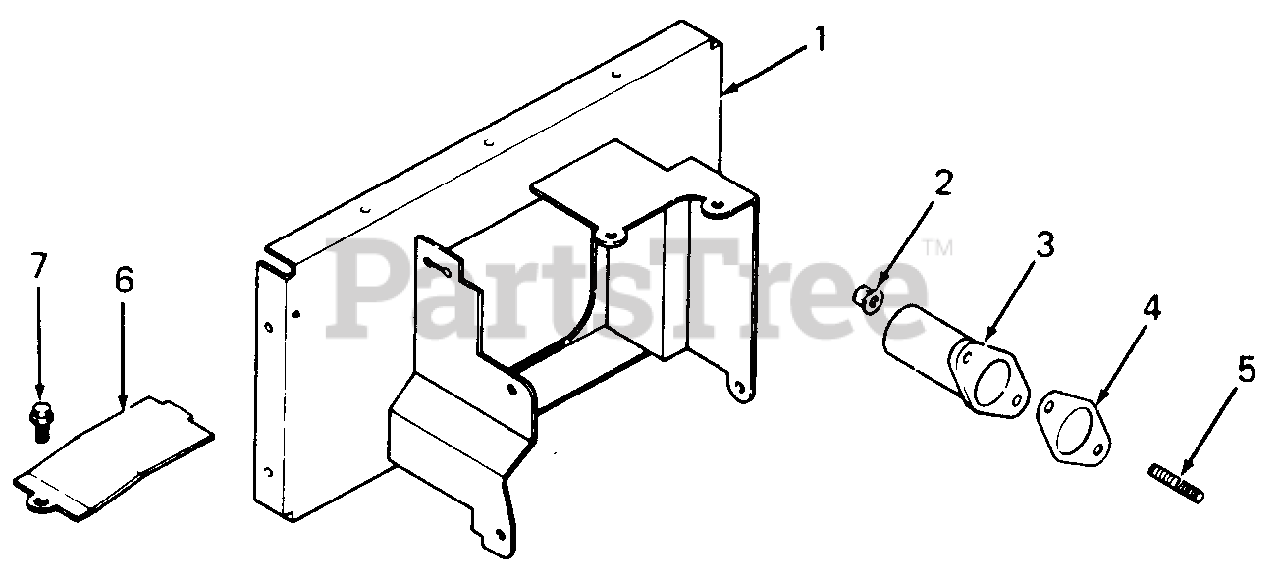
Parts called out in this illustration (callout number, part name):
1	Baffle, Ducted Air
2	Nut
3	Manifold, Exhaust
4	Gasket, Exhaust Manifold
5	Stud, Exhaust Manifold, M8 X 1.25 X 20
6	Cover, Baffle
7	Screw, M5 X 0.8 X 10
